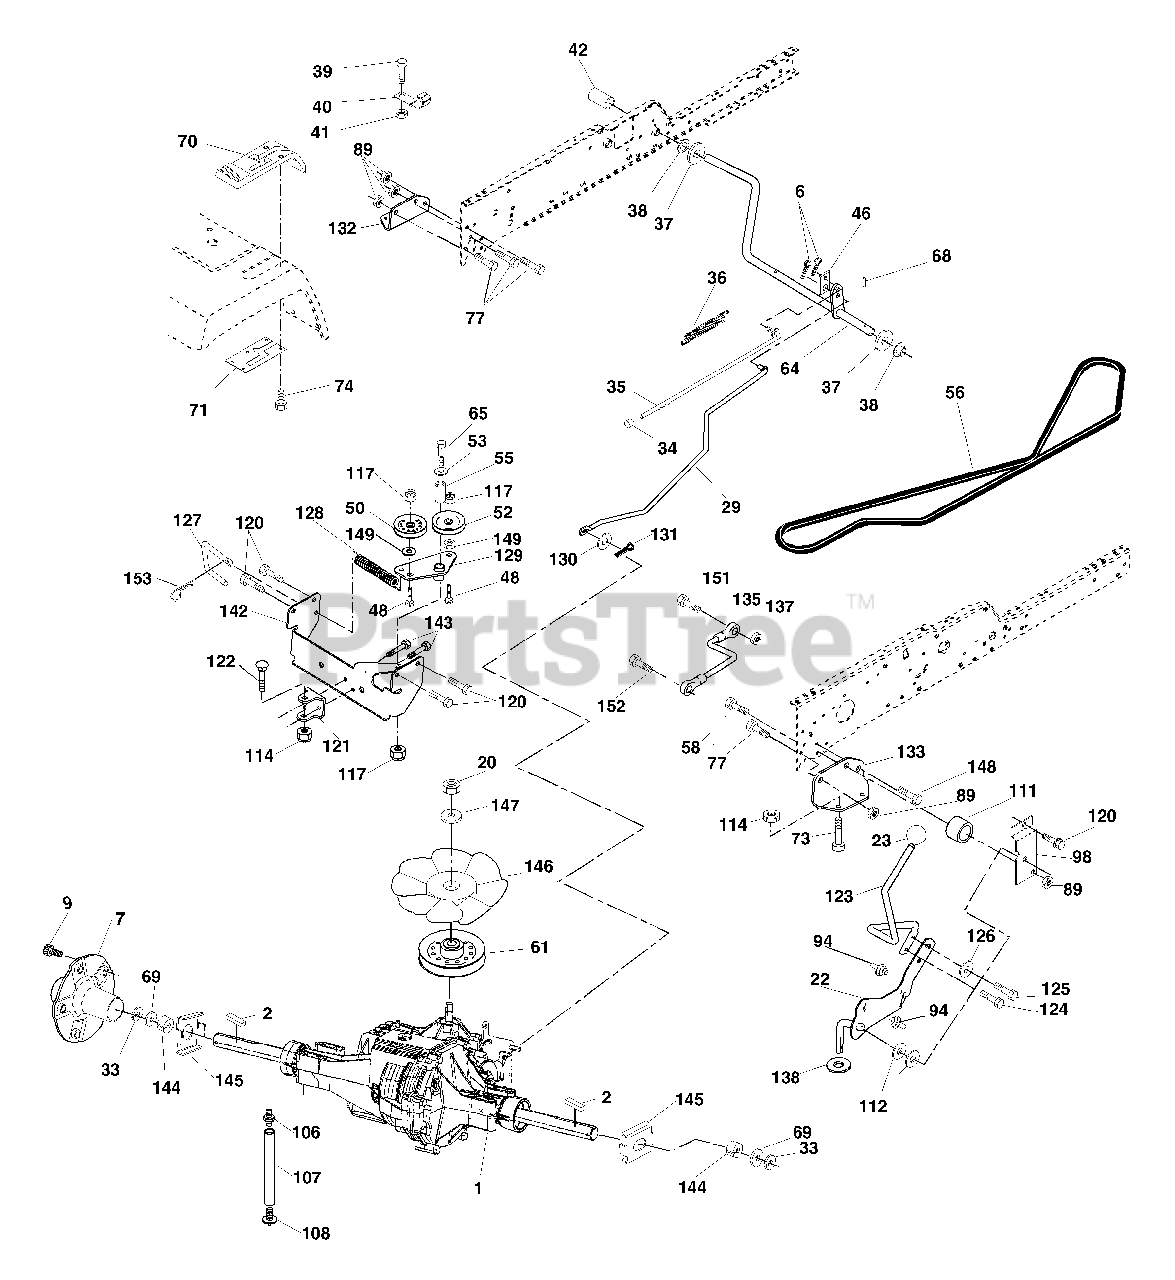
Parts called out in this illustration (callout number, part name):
2	Key Sq. 1/4 x 1/4 x 2
6	Pin, Cotter
7	Wheel, Hub Assembly
9	Bolt, Hub
20	Nut
22	Lever Asm Shift
23	Knob
29	Brake, Rod
33	Ring E
34	Cap, Parking Brake
35	Rod, Parking Brake
36	Spring, Drive Ground
37	Washer 25/32 x 1-1/4 x 16 Ga.
38	Nyliner
39	Screw, Fin. #10-24 x 1
40	Actuator, Interlock Switch
41	Nut Centerlock 10-24 Unc
42	Cover, Pedal
46	Retainer,Spring
48	Bolt Carr. Shoulder 3/8-16 x 1-3/4 Gr. 5
50	Pulley, Idler, Flat
52	Pulley, Idler, Grooved
53	Washer,Hardened
55	Bearing, Idler
56	V-Belt
58	Bolt Fin Hex 7/16-14 x 1-1/2
61	Pulley, Transaxle
64	Shaft, Brake Pedal
65	Bolt, Shoulder
68	Pin, Roll
71	Plate Console Shift
73	Bolt Hex Flghd 5/16-18 x 3 Gr5
74	Screw Hex Wsh. Hi-Lo 1/4-1/2
77	Bolt Fin Hex 7/16-14 x 1
89	Nut Crownlock 7/16-14 Unc
94	Fastener Christmas Tree
98	Bracket Shift
106	O-Ring Asm Hydro Gear
107	Line Fuel Hydro 15" VGT
108	Cap Asm Vent Hydro Gear
111	Spacer Shift Lever VGTH
112	Washer Nylon High Temp
114	Nut Lock Hex W/Ins 5/16-18 Unc
117	Nut, Lock Flg. 3/8-16
120	Screw 3/8-16 x .75
121	Bracket Strap Torque
122	Bolt 5/16-18 x 2.50
123	Rod Shift
124	Bolt Shoulder 5/16-18 x .561
125	Screw 5/16-18 x 5/8
126	Washer SRRTD 5/16 ID x 1.0 x .125
127	Link Control Clutch
128	Spring Drive GRND
129	Bracket Asm Idler Tensioning
130	Washer 13/32 x 5/8 x 16 Ga.
131	Pin Cotter 3/32 x 3/4
132	Bracket Mtg Hydro 3500 LH VGT
133	Bracket Mtg Hydro 3500 RH VGT
135	Link Asm Control Hydro 3500
137	Nut Lock 5/16-18 NC Thd.
138	Washer Thrust 5/8 x 1.10 x 1/32
142	Strap Torque HG-3500
143	Screw 5/16-18 x 3/4
144	Washer Spacer Axle HG-3000
145	Washer Axle Flange HG-3000
146	Fan 7" Hydro
147	Washer
148	Screw 3/8-16 x 1.0
149	Washer 13/32 x 7/8 x 10 Ga.
151	Bolt Fin Hex 5/16-18 x 7/8
152	Bolt Hex 5/16-18 x 1
153	Spring Retainer
